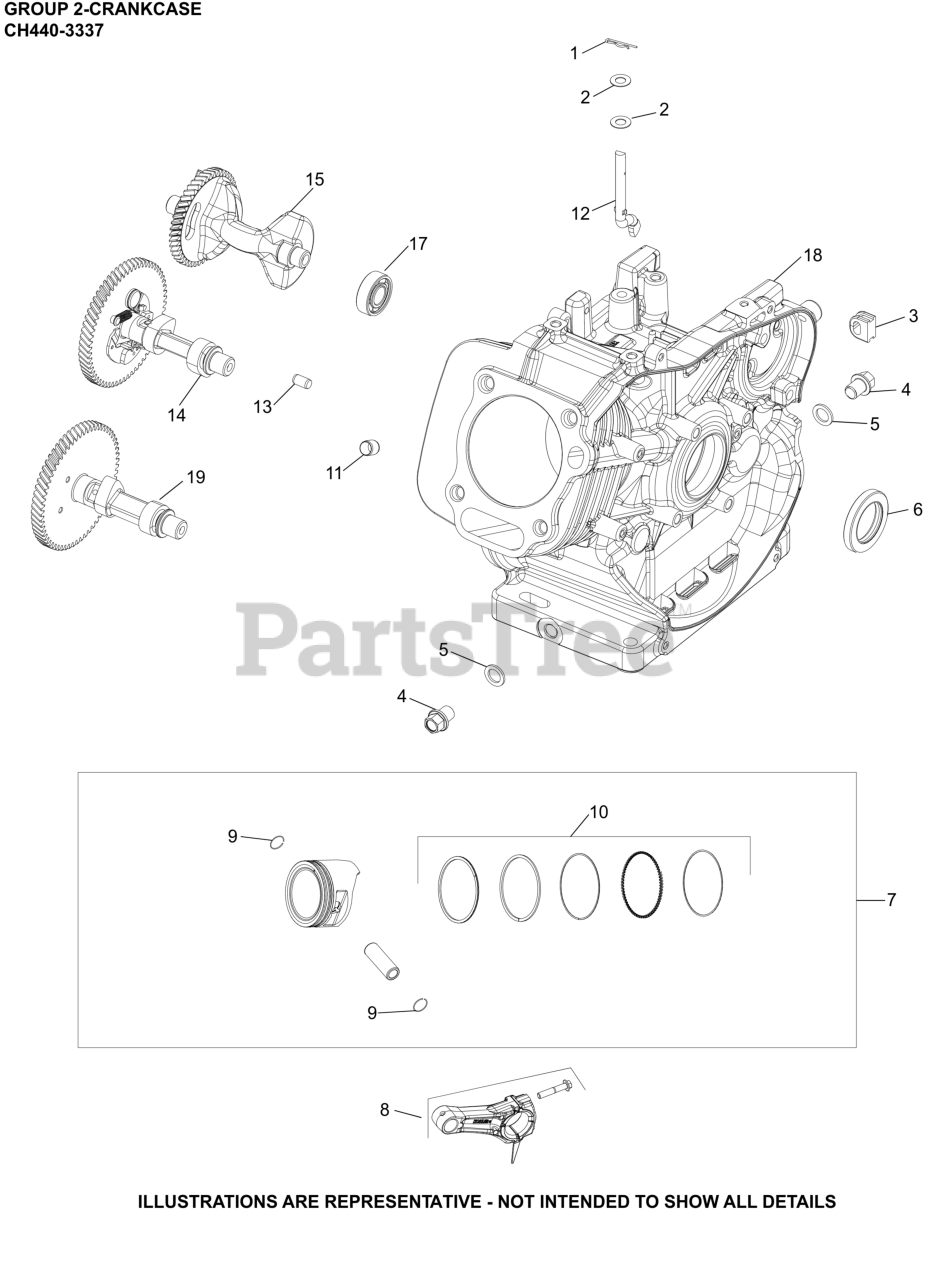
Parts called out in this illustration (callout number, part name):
1	CLIP, GOVERNOR SHAFT
2	WASHER, FLAT
3	GROMMET, CRANKCASE
4	KIT, DRAIN PLUG
5	WASHER, DRAIN PLUG
6	SEAL, CRANKSHAFT
7	KIT, PISTON W/RING SET (STD)
7	KIT, PISTON (0.25 O.S.)
8	ROD, CONNECTING ASSEMBLY
9	RETAINER, PISTON
11	PIN, DOWEL CYLINDER HEAD
12	SHAFT, GOVERNOR CROSS
13	PIN, DOWEL
14	CAMSHAFT ASSEMBLY
15	SHAFT, BALANCE
17	BEARING, BALANCE SHAFT
18	CRANKCASE
19	CAMSHAFT, NO ACR
